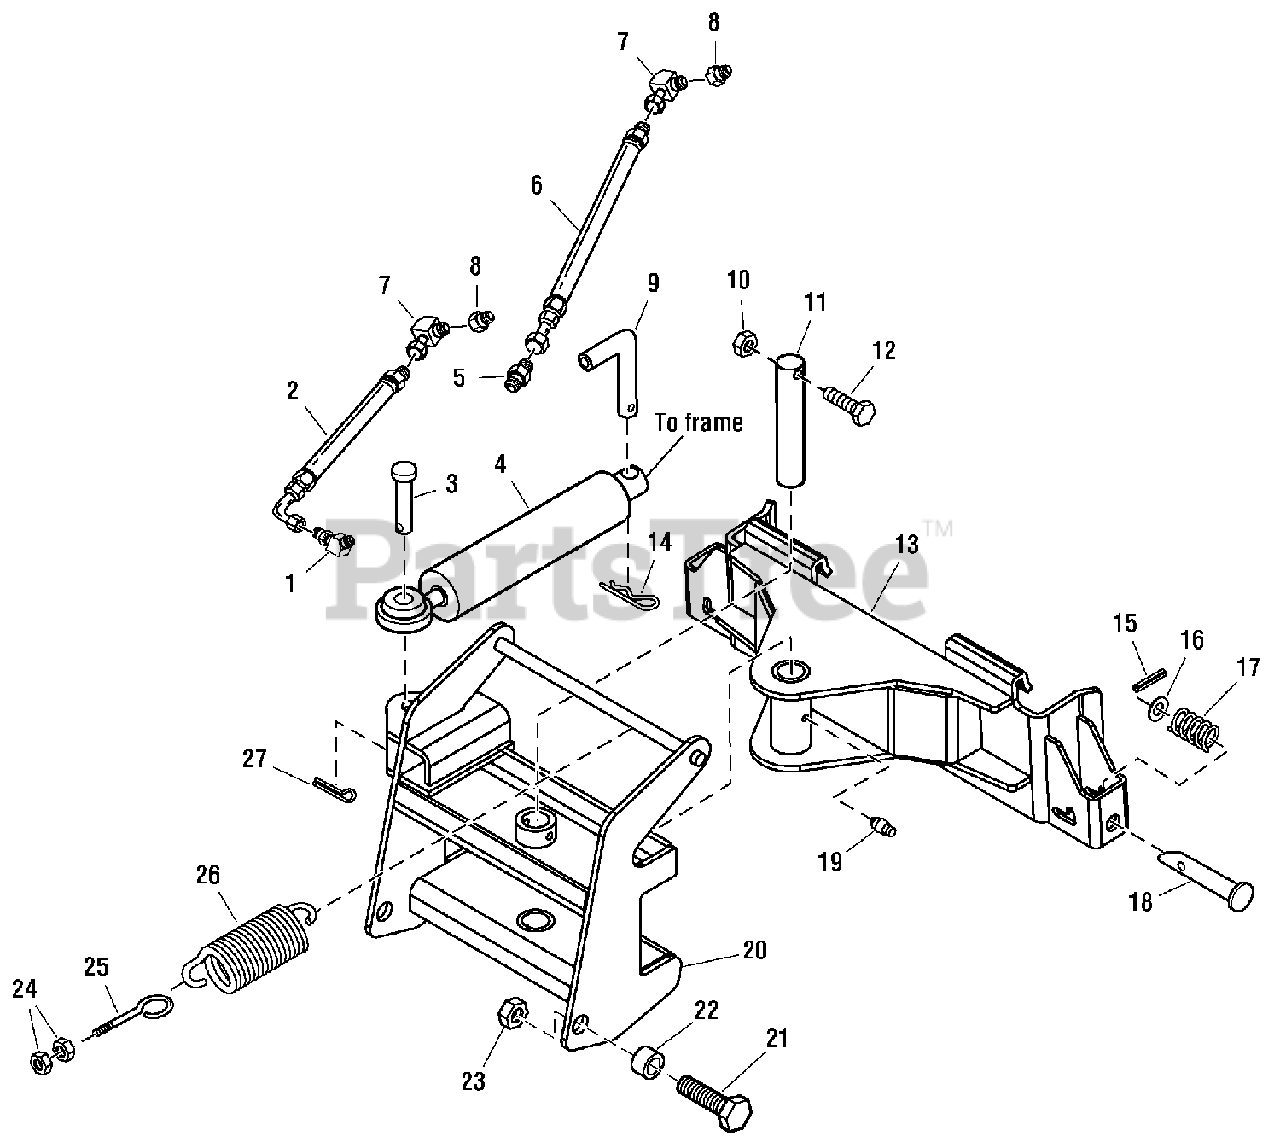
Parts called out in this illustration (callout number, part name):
1	FITTING, Elbow, 1/8NPTx 1/2-20
2	HOSE ASSEMBLY, 30" Long
3	PIN, Clevis
4	CYLINDER, Hydraulic
5	FITTING, Male, 1/8NPT x 7/16-20
6	HOSE ASSEMBLY
7	FITTING, Elbow, Swivel, 1/4-18
8	NOSE PIECE ASSEMBLY
10	NUT, Hex Lock ESNA, 1/4-20
12	CAPSCREW, Hex Head, 1/4-20 x 2
13	HITCH ASSEMBLY
14	CLIP, Hair Pin
15	PIN, Roll
16	WASHER, 5/8
17	SPRING, Compression
18	PIN, Flat Head, Drilled
19	FITTING, Lube
20	FRAME ASSEMBLY
21	CAPSCREW, Hex Head, 1/2-13 x 1-1/2
23	NUT, Hex Centerlock, 1/2-13
24	NUT, Hex, 5/16-18
26	SPRING, Extension
27	PIN, Cotter
